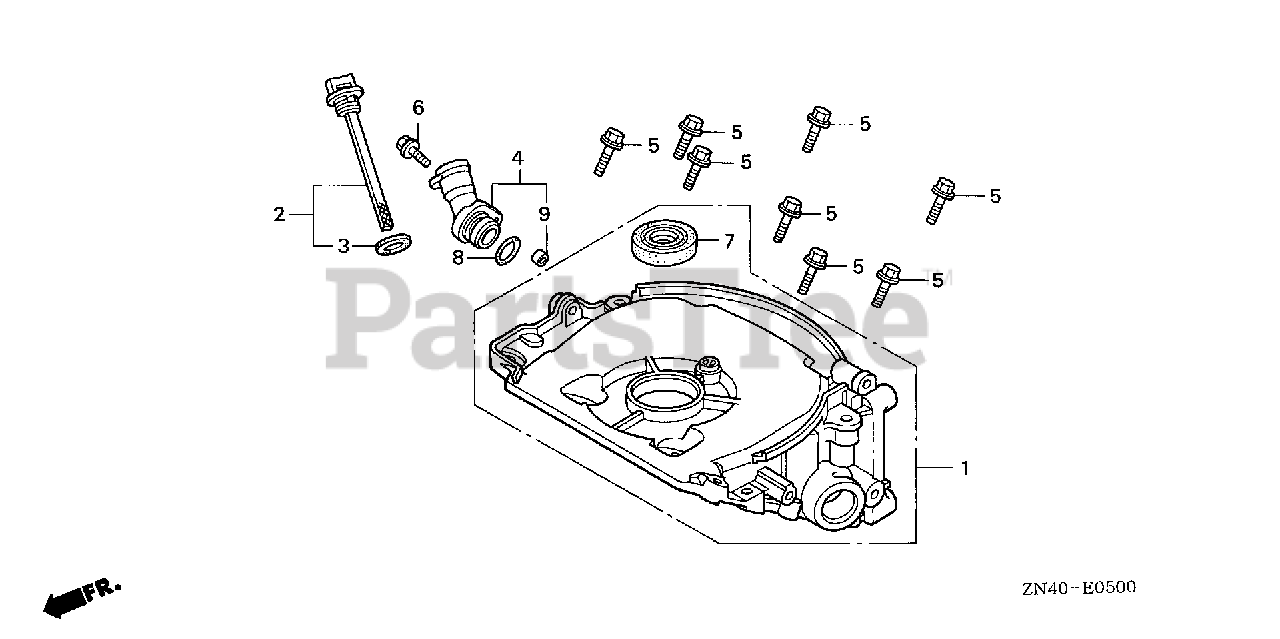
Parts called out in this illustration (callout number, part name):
1	CASE ASSY., OIL
2	CAP ASSY., OIL FILLER
3	GASKET, OIL FILLER CAP
4	EXTENSION, OIL FILLER
5	BOLT, FLANGE (5X23)
6	BOLT, FLANGE (5X14)
7	OIL SEAL (17X27X5) (KOYO)
8	O-RING (21.2X2.4) (ARAI)
9	COLLAR, TOP COVER
